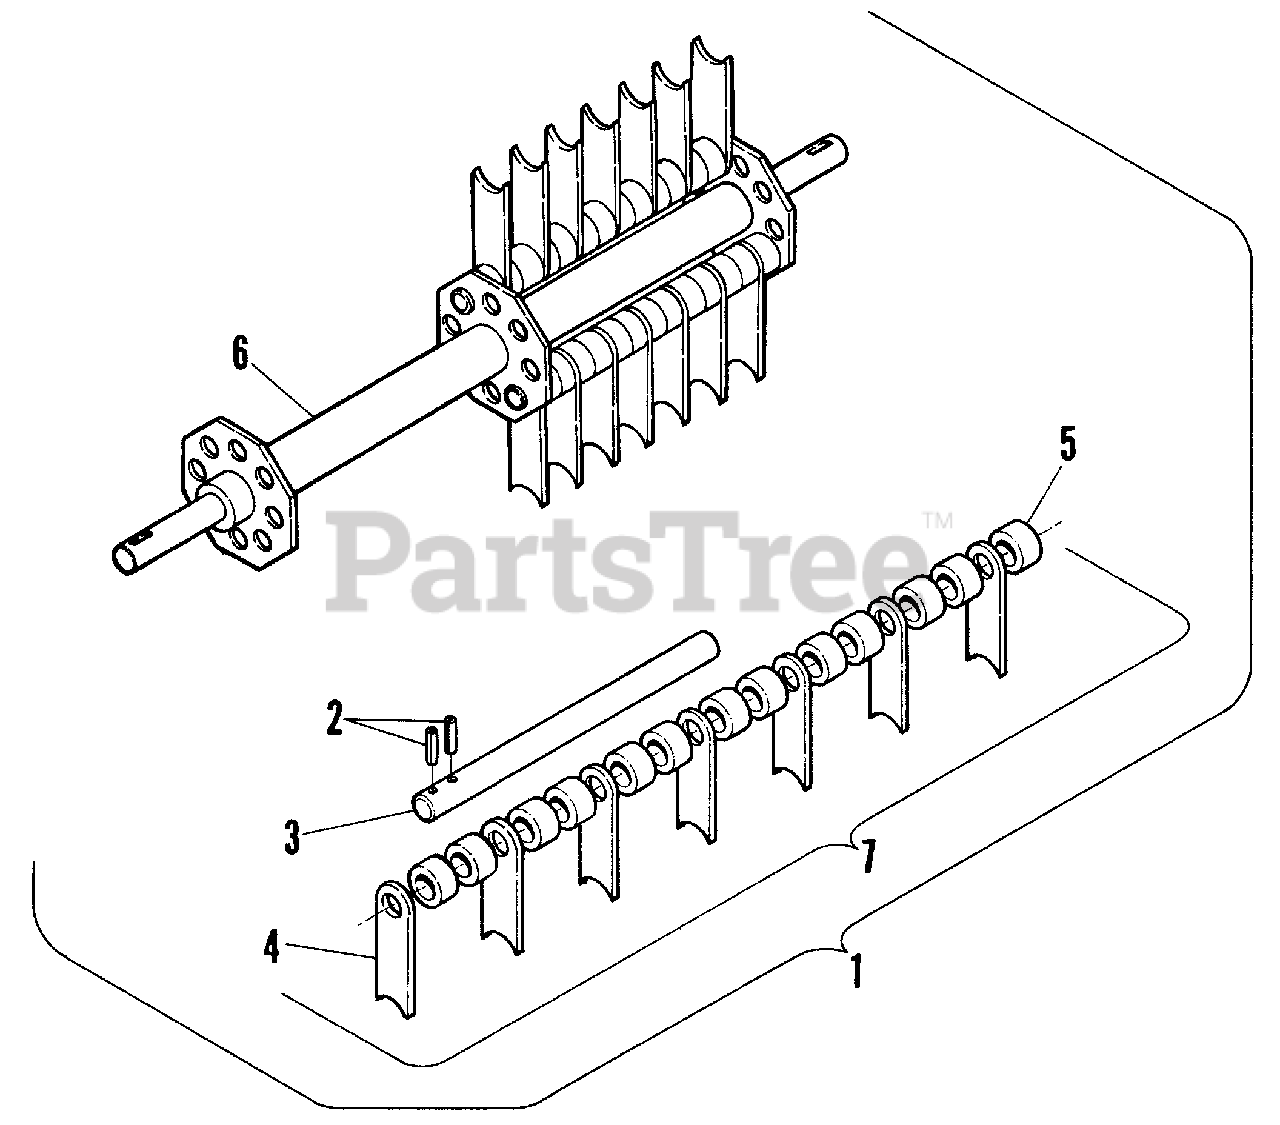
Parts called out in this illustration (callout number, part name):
1	RAKING SHAFT, Complete
2	PIN, 1/8 x 7/8" Roll
3	SATELLITE SHAFT
4	FINGER
5	SPACER
6	SHAFT ASSEMBLY
7	MAIN SHAFT REPLACEMENT KIT
